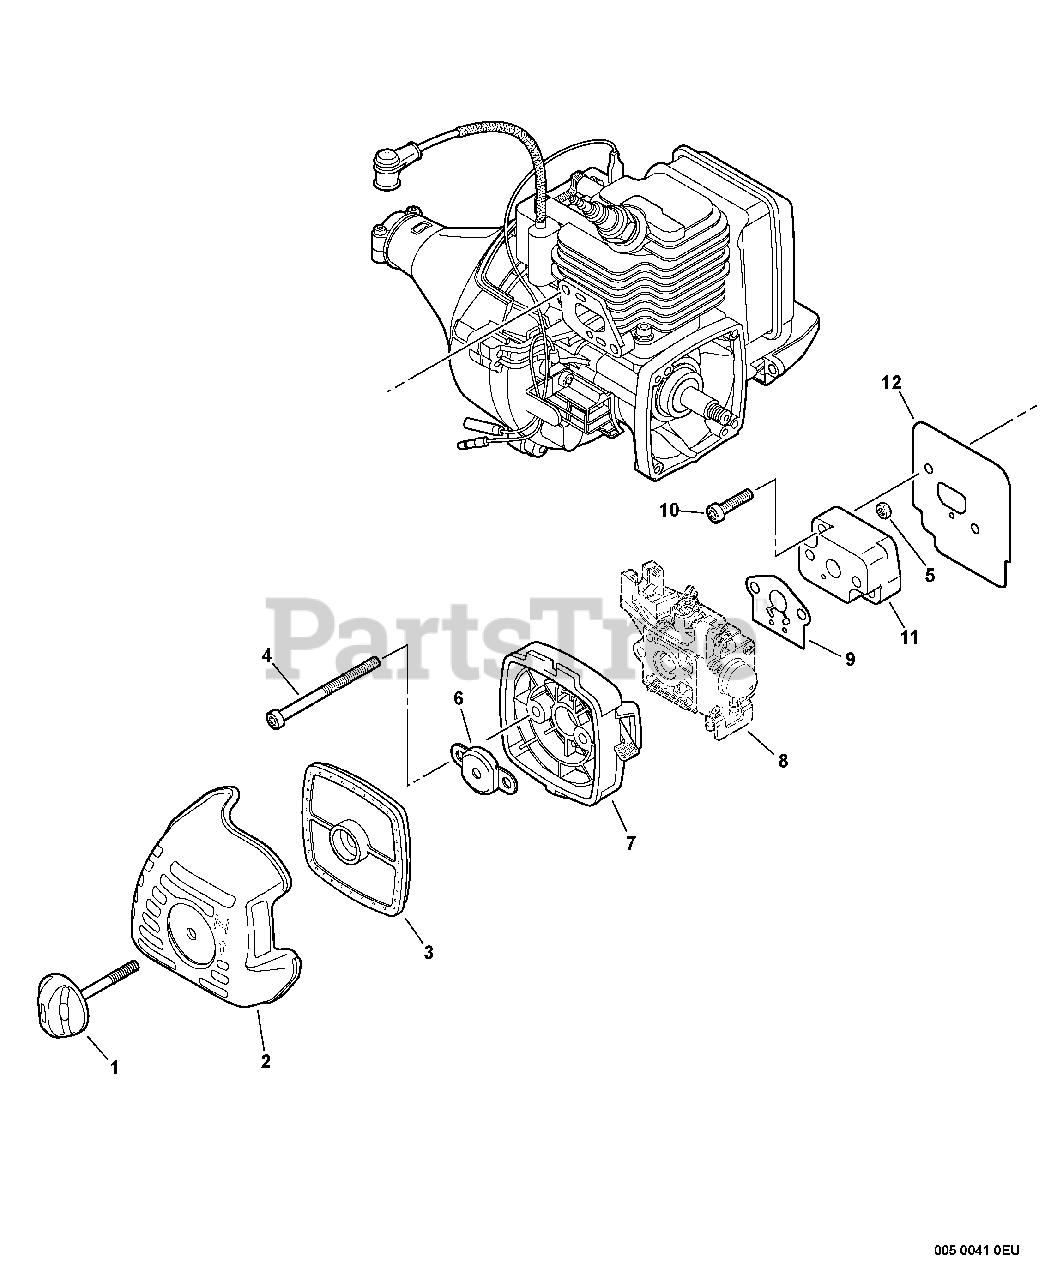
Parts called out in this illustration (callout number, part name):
1	THUMBSCREW
2	COVER, AIR FILTER
3	FILTER, AIR - SINGLE LAYER
4	SCREW - 5X65
6	PLATE, PREVENT
7	CASE, AIR FILTER
8	CARBURETOR
9	GASKET, INTAKE
10	SCREW - 5X20
11	INSULATOR, INTAKE
12	SHIELD, INTAKE
